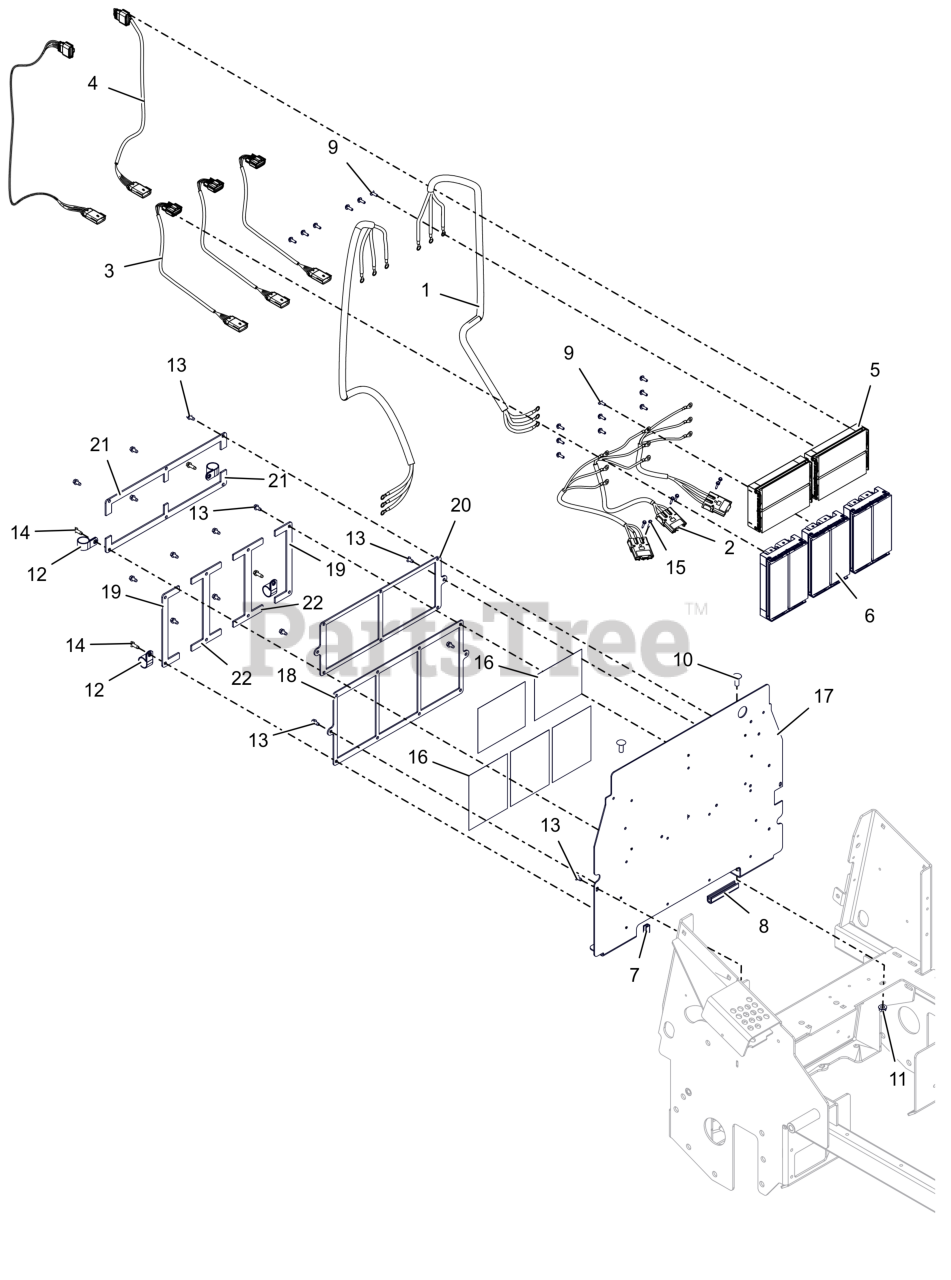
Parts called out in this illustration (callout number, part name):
1	HARNESS, TRACTION PHASE
2	HARNESS, DECK PHASE
3	HARNESS, DECK SIGNAL
4	HARNESS, TRACTION SIGNAL
5	CONTROLLER, TM PSEV
6	KIT, MY23 48 DECK CONTROLLER
7	STRIP, COWL
8	GAURD- PLASTIC EDGE & TRIM
9	BLT,HEX M5-.8X16 EP30 G8.8 ZCC
10	BLT,RHSSN .38-16X1.00 G5 ZCC
11	NUT-LK-CTR-FLG .375-16 GF ZCC
12	CLAMP, COUSHIONED STEEL REV
13	SCR-TAP .25-20X.50 HWH ZCC
14	SCR,TAP .25-20X.75 HWH TR ZCC
15	SCR-TAP #6-32X.75 HWH ZCC
16	PAD, THERMAL
17	PANEL, CONTROLLER MTG
18	PLATE, HEAT SINK SPCR (BLACK)
19	PLATE, LOWER CONTROLLER MTG (BLACK)
20	PLATE, HEAT SINK SPCR (BLACK)
21	PLATE- UPPER CONTROLLER MTG
22	PLATE, LOWER CONTROLLER MTG (BLACK)
